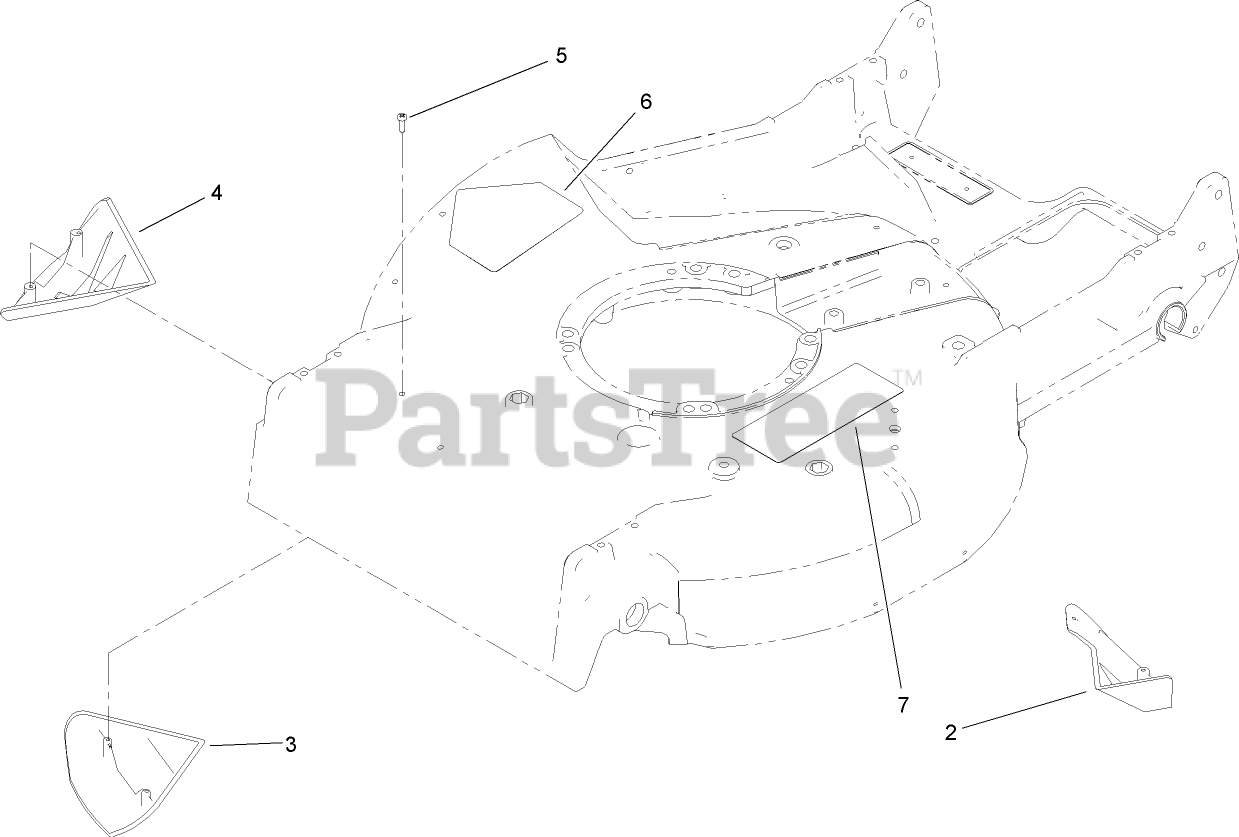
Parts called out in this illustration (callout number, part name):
2	KICKER-REAR
3	KICKER-FRONT
4	KICKER-RH
5	SCREW-PPH
6	DECAL-DANGER
7	DECAL-WARNING
